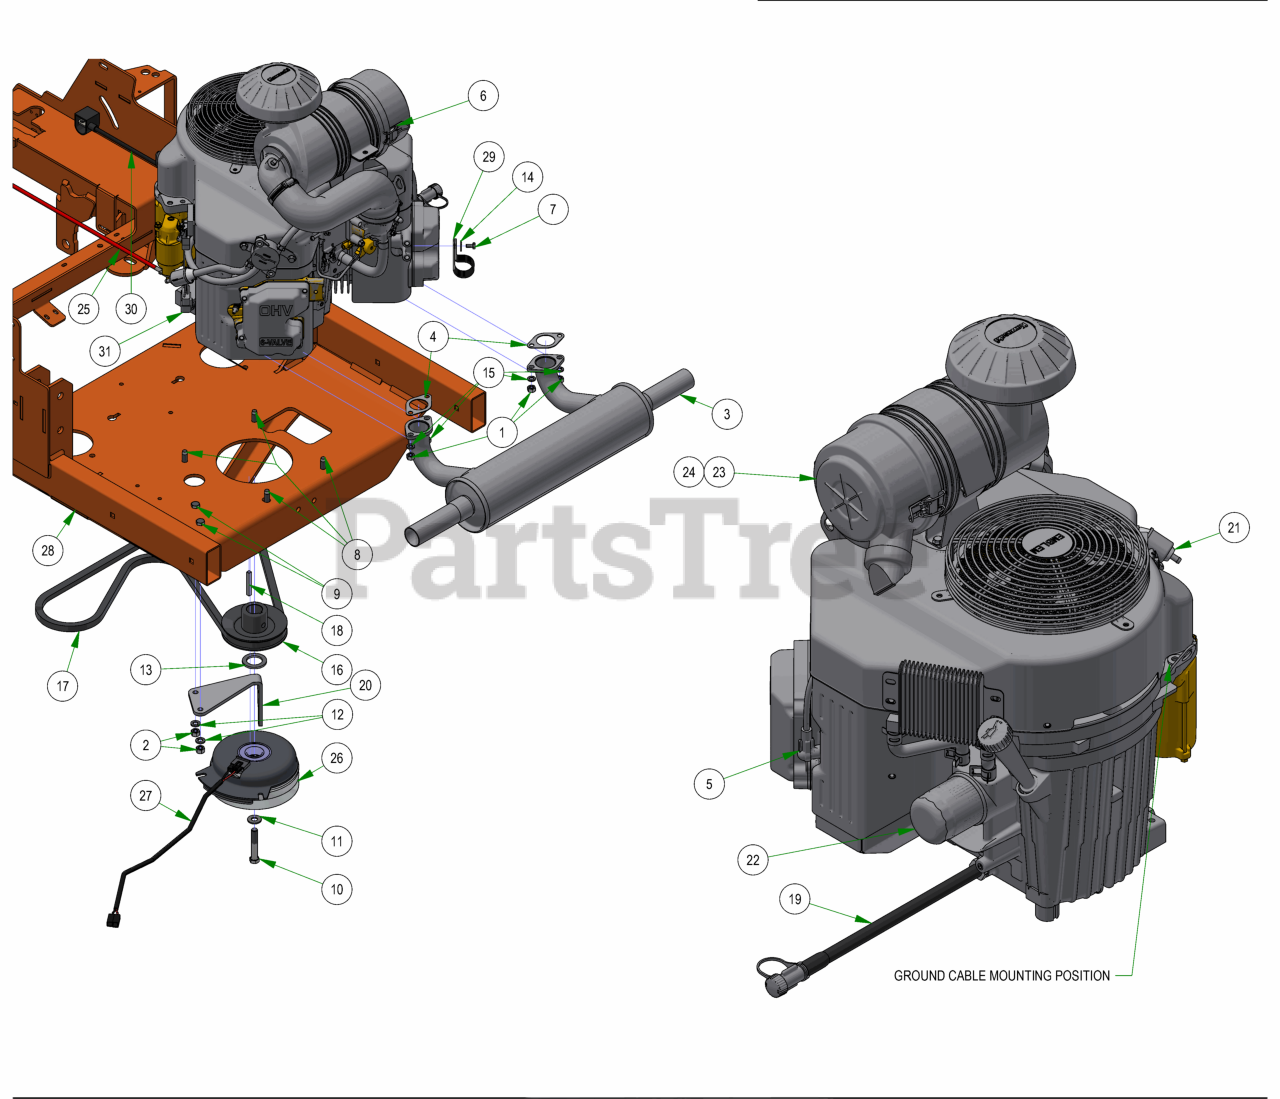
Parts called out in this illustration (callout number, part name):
1	M8-1.25 DIN 934 HEX NUT (CL.8) ZINC
2	3/8-16 HEX NUT ZINC
3	2019 Rebel/Rogue Kawasaki 1000 Muffler
4	Exhaust Gasket
5	Spark Plug - Kawasaki
6	Kawasaki FX1000 Engine
7	M6-1.0 X 12MM DIN 933 HEX TAP BOLT (CL 8.8) ZINC
8	3/8-16 X 1-1/8 HEX WASHER UNSLOT SERRATED (TRI-LOB) TRS ZINC YELLOW
9	3/8-16 X 1-1/4 HEX CAP SCREW (GR.5) ZINC
10	7/16-20 X 2-1/2 HEX Bolt GR 8 W/ Patch
11	3/8 FLAT WASHER USS (1" OD) ZINC
12	3/8 SPLIT LOCKWASHER ZINC
13	1.140 ID X 1.750 OD X .132 THICK FLAT WASHER PLAIN
14	1/4 USS FLAT WASHER (3/4 OD) ZINC
15	5/16 SPLIT LOCKWASHER ZINC
16	4 3/4 Motor Pulley
17	2019 Rogue Pump Belt 68"
18	1/4 X 2 SQ MACHINERY KEY 1018 STL PLAIN
19	Kawasaki Oil Drain
20	PTO Engager Holder
21	Universal Inline Fuel Filter
22	Oil Filter
23	Canister Air Filter- Outer
24	Canister Air Filter- Inner
25	24" Red Battery Cable
27	Clutch Pigtail
28	2023 Rogue Frame - Painted
29	Diesel Hydraulic Hose Clamp
30	Starter Cable
31	2019 Harness Adaptor-Gen2 FX-ALL
